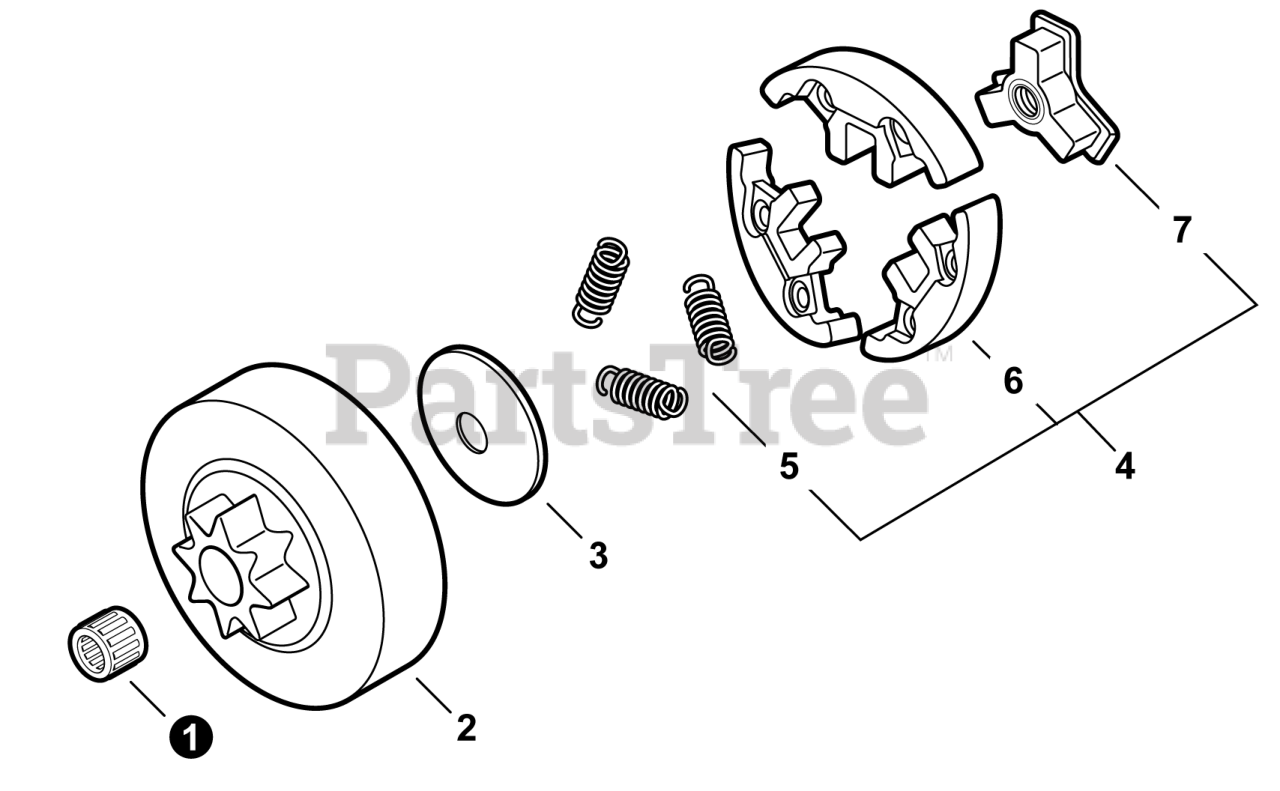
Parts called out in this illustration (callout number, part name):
1	BEARING, NEEDLE 10
2	DRUM, CLUTCH
3	PLATE, CLUTCH
4	CLUTCH ASSY
5	SPRING, CLUTCH
6	CLUTCH SHOE SET
7	HUB, CLUTCH
